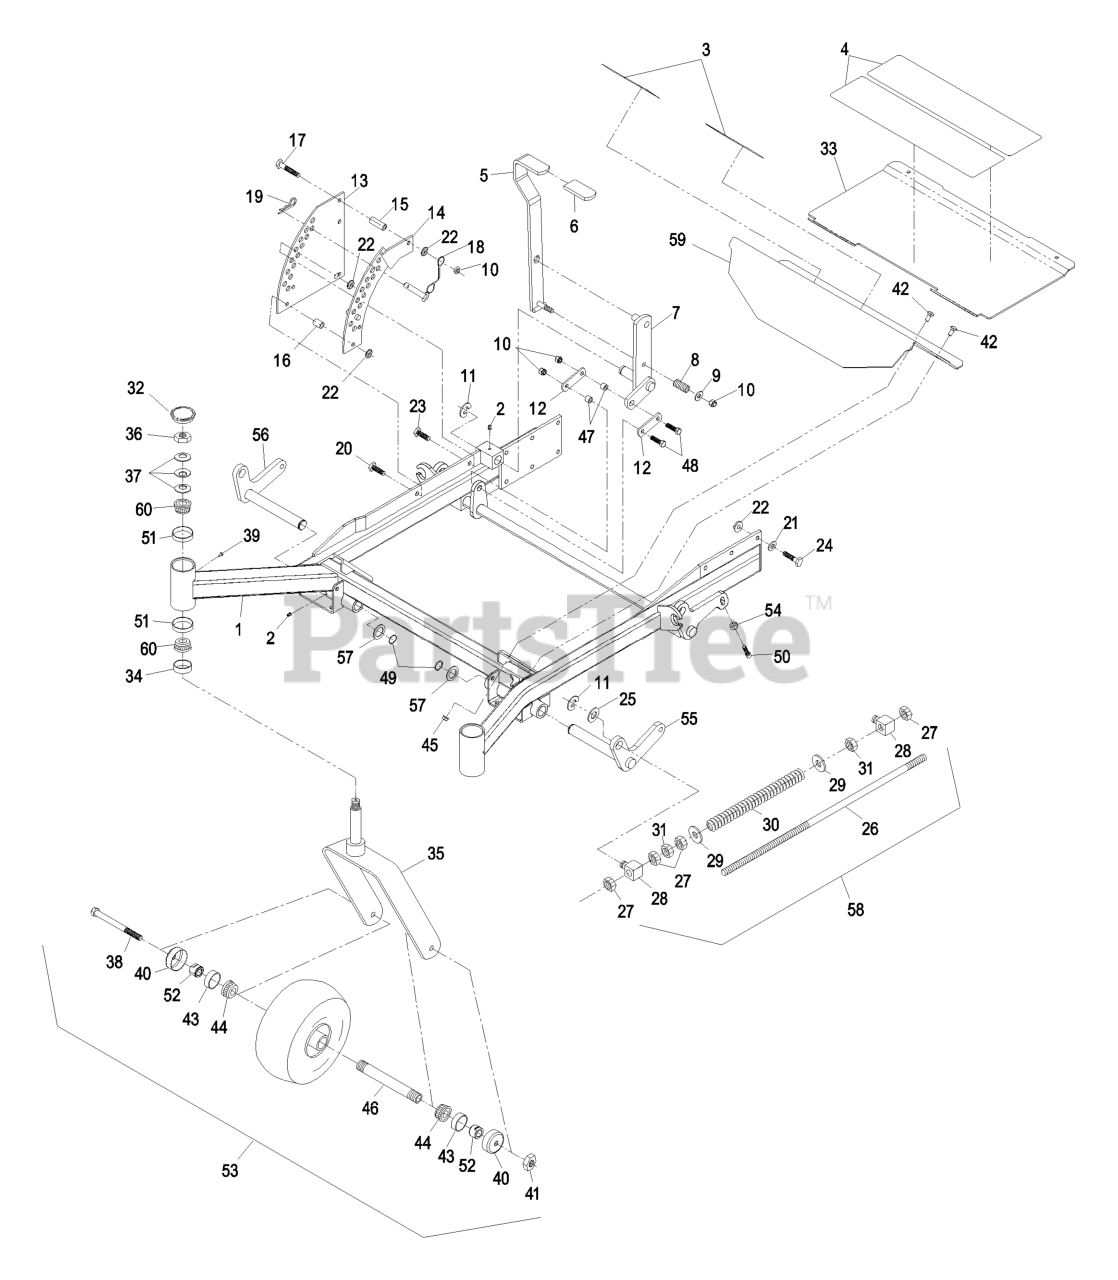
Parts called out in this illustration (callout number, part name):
1	KIT,FRONT FRAME LZ 52
2	FITTING-GREASE
3	PAD-ANTI SKID
4	PAD-ANTISKID
5	LIFT LEVER/GRIP ASM
6	GRIP-LEVER, LIFT
7	ARM-LIFT, DECK
8	SPRING-COMPRESSION
9	WASHER-FLAT
10	NUT-LOCK, NI
11	RING-RETAINING, EXT
12	ARM-LIFT, DECK
13	PLATE-LIFT, DECK
14	Plate Wldmt, Deck Lift
15	BUSHING-LEVER, LIFT
16	BUSHING-LEVER, LIFT
17	SCREW-HH
18	PIN-HITCH (W/LANYARD)
19	PIN-COTTER
20	SCREW-HH
21	WASHER-BELLEVILLE
22	NUT-HHF, WHIZ
23	SCREW-HH
24	SCREW-HH
25	WASHER-FLAT
26	ROD-LIFT, DECK
27	NUT-HEX
28	SWIVEL-DECK MOUNT, REAR
29	WASHER-FLAT
30	SPRING-SUPPORT, DECK
31	NUT-JAM
32	CAP-GREASE
33	ASM,LIFTOUT FLOORPAN/PAD
34	SEAL-GREASE
36	NUT-LOCK, NI
37	WASHER-BELLVILLE
38	SCREW-HH
40	GUARD-SEAL
41	NUT-LOCK, NI
42	BOLT-CARR
43	SEAL-CASTER
44	BEARING-CONE, TAPERED ROLLER
47	BUSHING
48	SCREW-HH
49	RING-RETAINING
50	SCREW-HSH
51	CUP-BEARING
52	SPACER-NUT
53	ASM, WHEEL AND TIRE W/ AX
54	NUT-JAM
55	WLD, FRONT LIFT SHAFT - L
56	WLD,FRONT LIFT SHAFT RH
57	WASHER-SPACER
58	FRONT FRAME SPRING ASM
60	Cone-Bearing Tapered Roller
